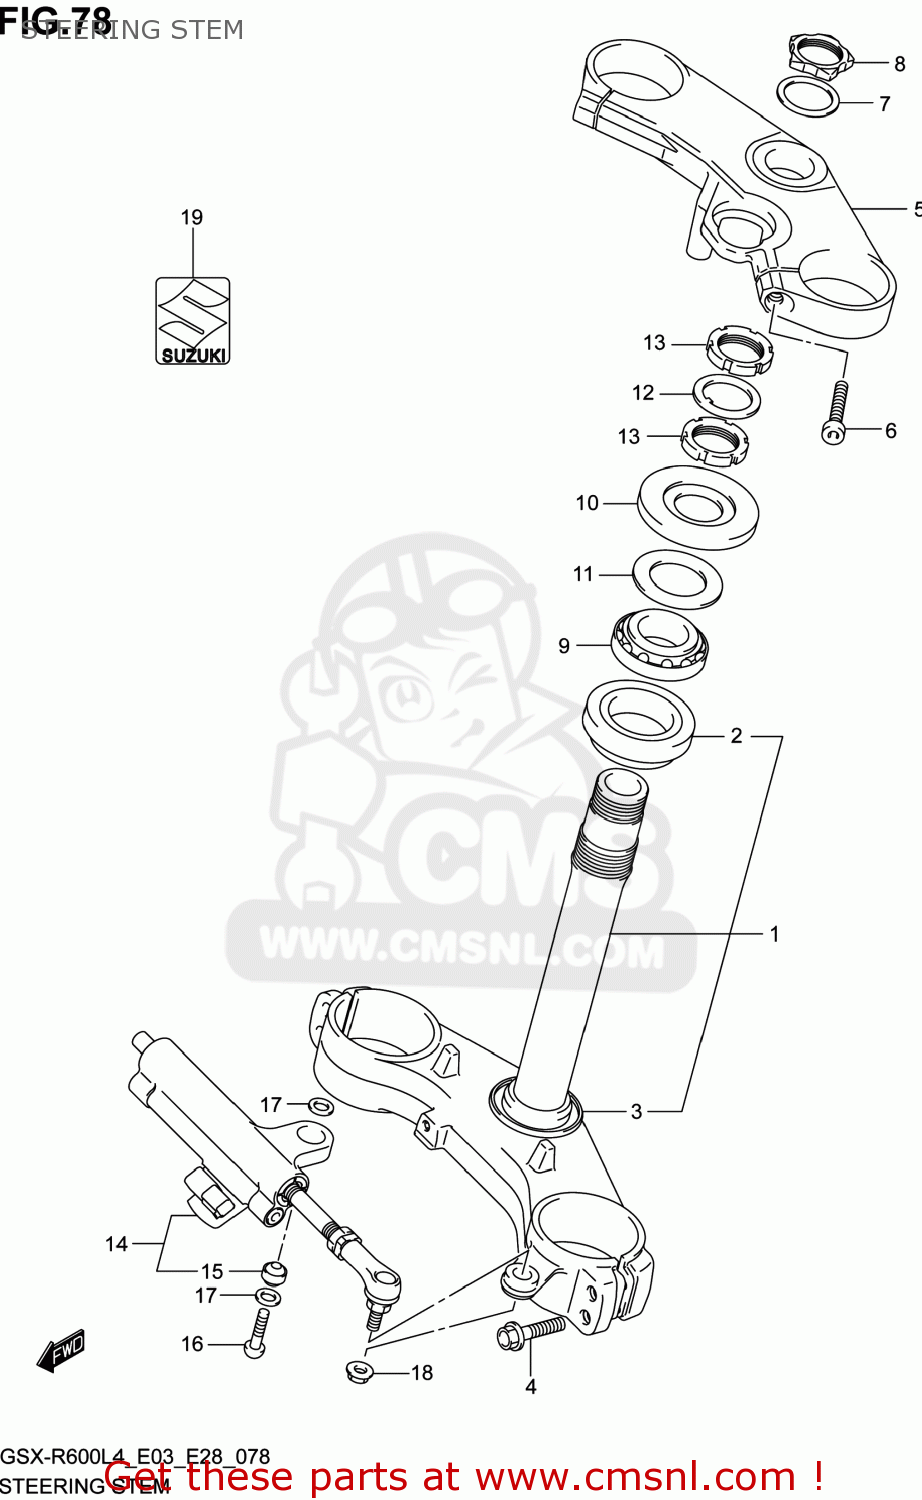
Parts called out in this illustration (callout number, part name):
1	STEM,STEERING
2	BEARING(30X55X17)
3	SEAL,STEERING LWR
4	BOLT,HOLDER AXLE(8X40)
5	HEAD,STEERING STEM
6	BOLT,HOLDER(8X25)
7	WASHER,STEM HEAD
8	NUT,STEM HEAD
9	BEARING(30X55X17)
10	COVER,STEERING UPR
11	SEAL,STEERING LWR
12	WASHER,STEERING STEM
13	NUT,STEERING STEM
14	DAMPER ASSY,STEERING
15	BEARING(8X17.5X11)
16	BOLT(8X35)
17	SEAL,PILLOW BALL,DUST
18	NUT
19	EMBLEM,"S"
